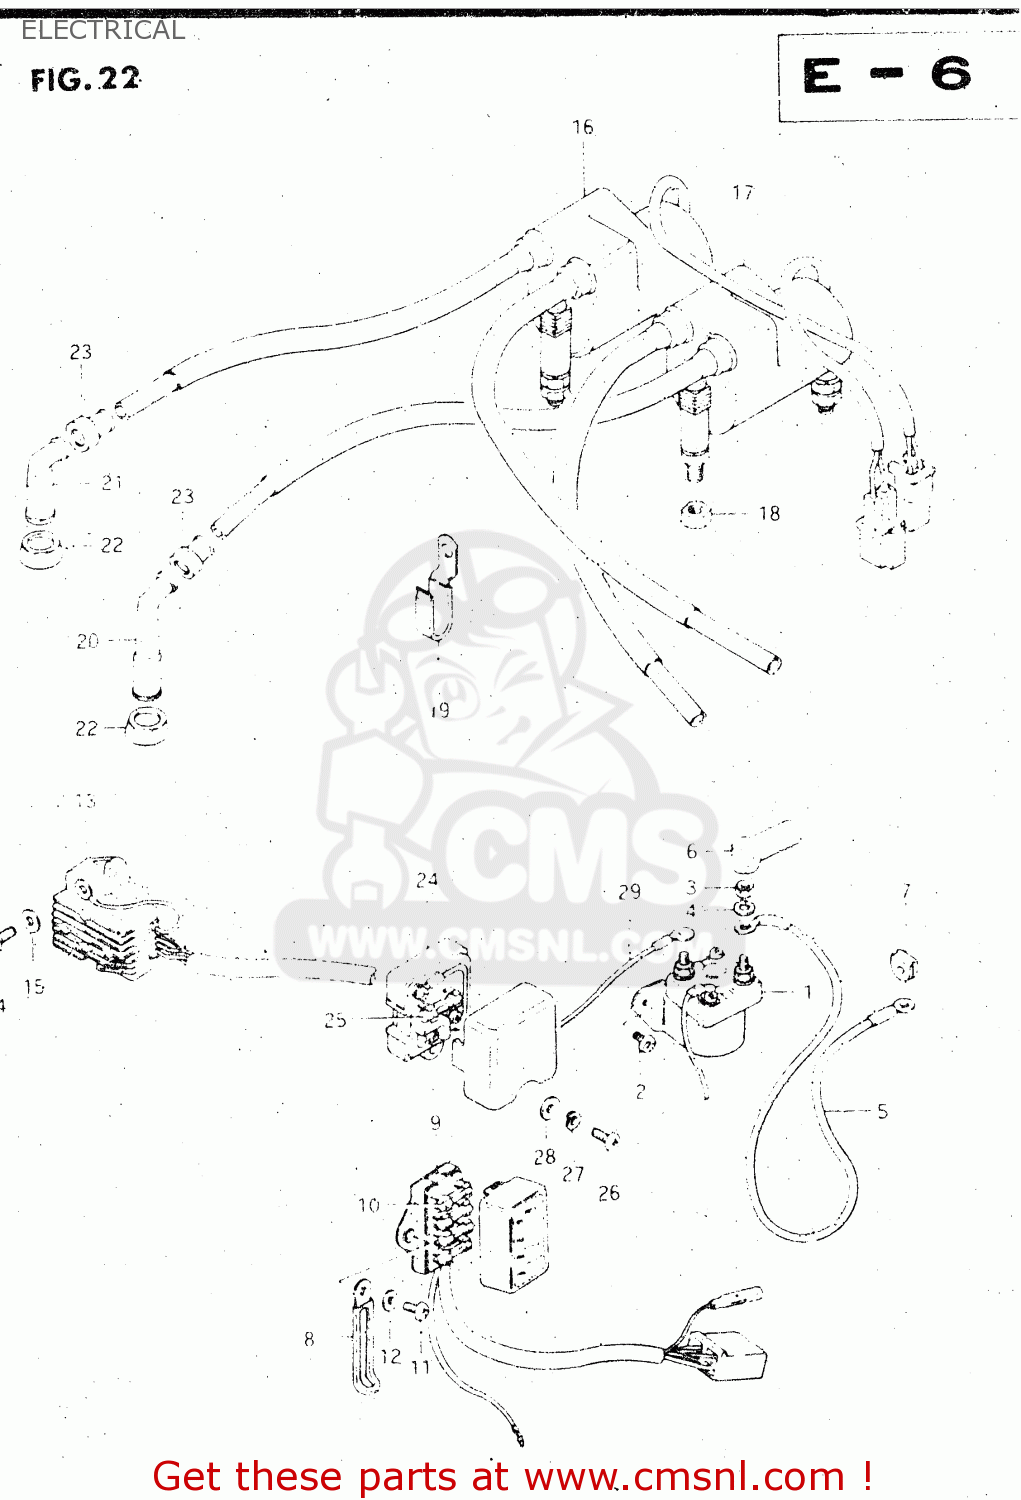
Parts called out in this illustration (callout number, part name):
1	RELAY ASSY,STARTING MOTOR
2	SCREW
3	NUT 6MM
4	LOCK WASHER
5	WIRE,STARTER MOTOR LEAD
6	CAP,STARTER RELAY
7	GROMMET,STARTER CABLE
8	CLAMP
9	BOX ASSEMBLY,FUSE
10	FUSE(15A)
11	SCREW 6X12
12	WASHER
13	RECTIFIER ASSEMBLY
14	SCREW
15	WASHER
16	COIL ASSEMBLY,IGNITION
17	COIL ASSEMBLY,IGNITION
18	NUT
19	CLAMP
20	CAP ASSY,SPARK PLUG
21	CAP,SPARK PLUG
22	SEAL,SPARK PLUG
23	SEAL,SPARK PLU
24	TERMINAL ASSEMBLY,POWER SO
25	FUSE(10A)
26	SCREW
27	LOCK WASHER
28	WASHER
29	WIRE
